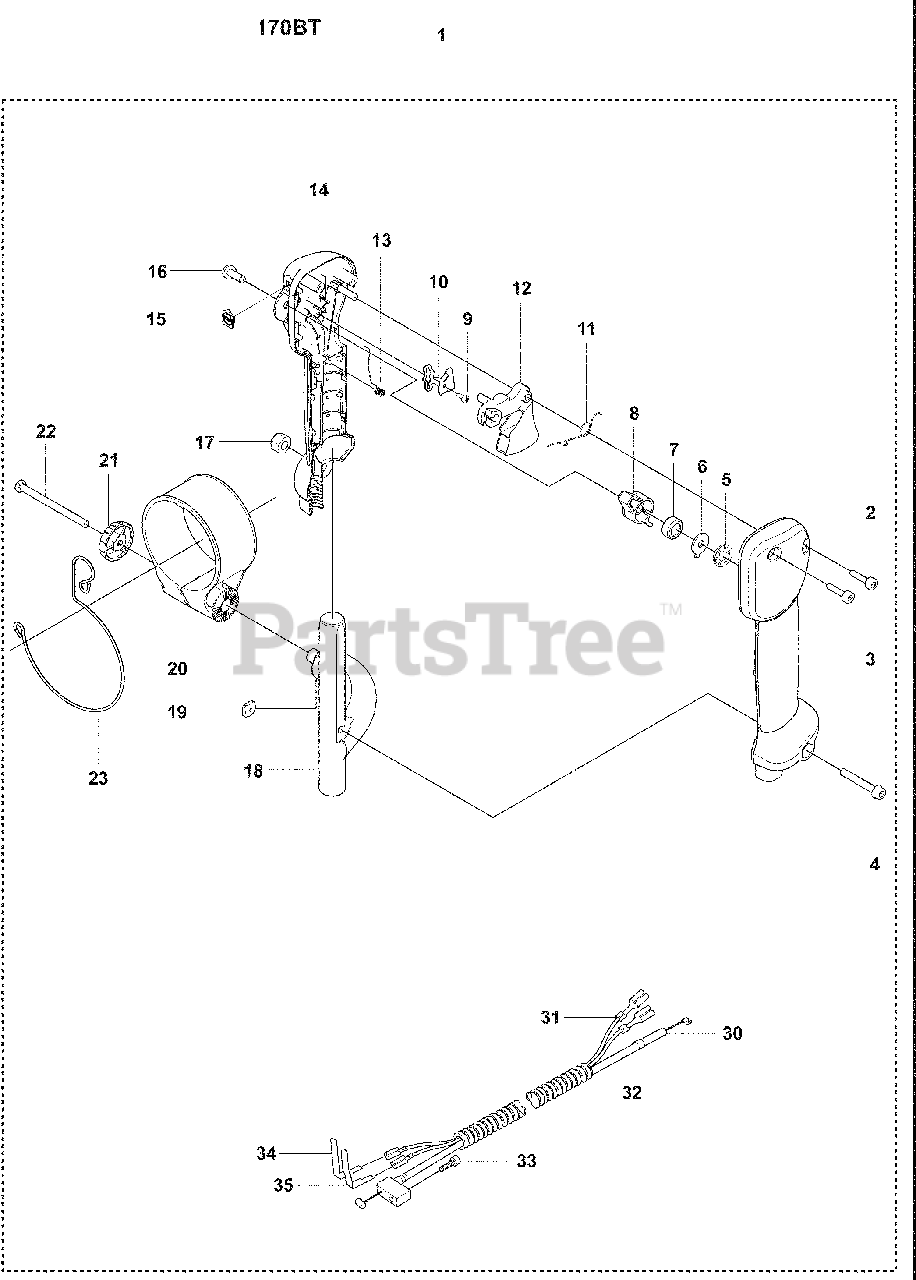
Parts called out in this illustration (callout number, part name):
1	HANDLE ASSY 170BT
3	Right Half Handle
4	Screw, Ihscfm M5 X 35 10.9 ZP
7	Spring, Rubber
8	Stop Lever
14	Left Half Handle
19	Square Nut
20	HOLDER TH
21	Air Filter Cover Knob
30	Cable, Complete
31	Cord
34	Contact Spring
35	Contact Spring
